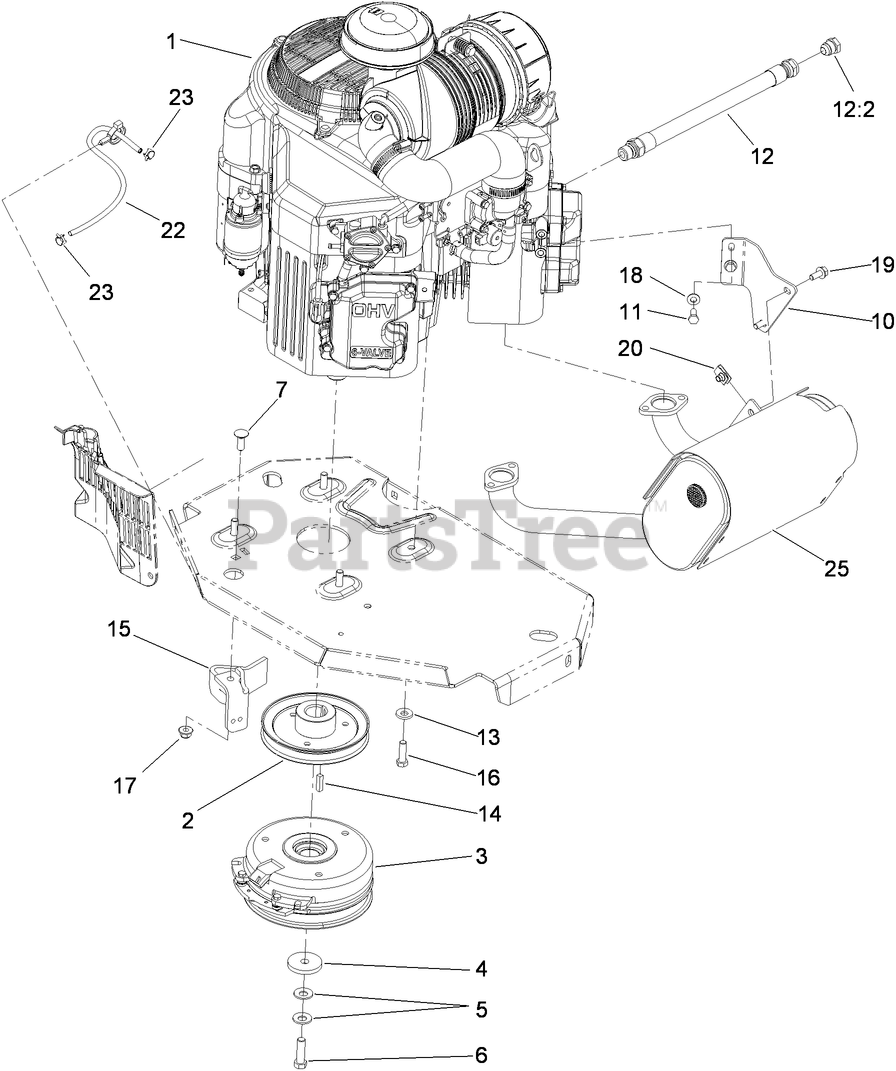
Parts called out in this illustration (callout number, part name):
2	SHEAVE
3	CLUTCH KIT
4	WASHER-CLUTCH
5	WASHER-SPRING
6	SCREW-HH, W/LOCTITE
7	SCREW-CARR
10	BRACKET-MUFFLER
11	SCREW-HH
12	OIL DRAIN HOSE ASM
13	WASHER-BELLEVILLE
15	CLUTCH-ANCHOR
16	SCREW-HH
17	NUT-HF, NI
18	WASHER-SPRING
19	SCREW-HHF
20	NUT-U
22	HOSE-FUEL
23	CLAMP-HOSE
25	MUFFLER
